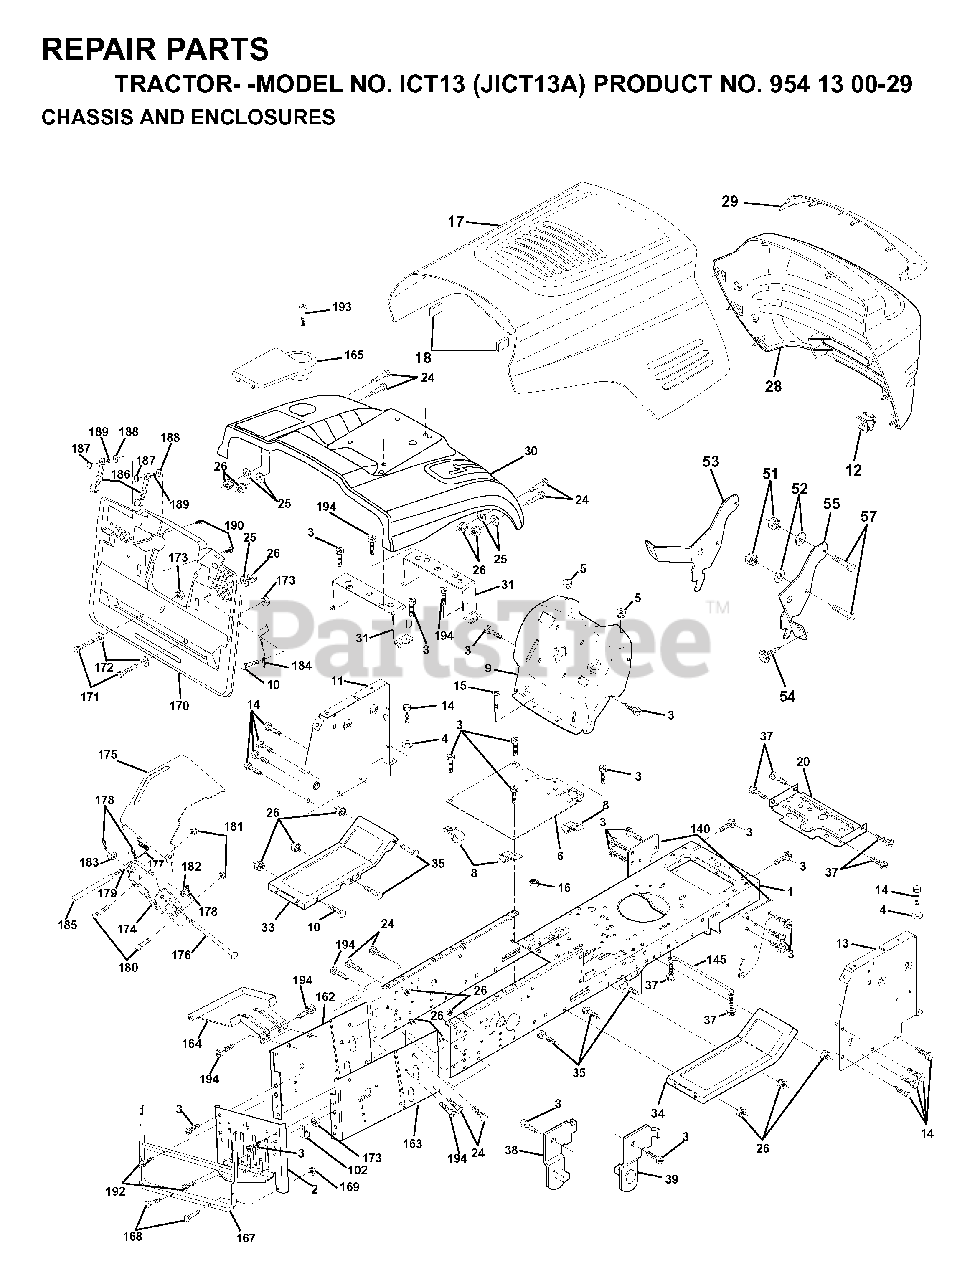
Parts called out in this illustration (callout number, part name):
3	SCREW
5	BUMPER.RUBBER.HOOD
6	SADDLE FLAT
8	CLIP,INSULATOR
10	BOLT D
11	PANEL DASH LH
13	DASH PANEL
16	NUT
18	BUMPER HOOD T
20	PLATE MTG
25	WASHER
26	NUT
31	BRACKET SUPPORT FENDER
38	BRACKET LH PIVOT
39	BRACKET RH PIVOT
51	LOCKNUT
57	BOLT
102	CLIP T
140	BRACKET SUSPENSION FRONT
145	ROD PIVOT CHASSIS/HOOD
164	SUPPORT
168	BOLT.ROUND.HEAD.SQUARE.NECK
169	NUT T
170	COVER BACKPLATE
172	WASHER
176	HINGE PIN
177	SPRING COVER LH
178	COTTER PIN
179	ROD PIVOT
180	BOLT RB
181	LOCKNUT
184	BRACKET
185	TUBE LEVER
186	LATCH ASSY
187	WELDNUT
189	LOCKWASHER
190	SCREW
192	SCREW LT
193	SCREW LT
194	SCREW 3/8-16X3/4
